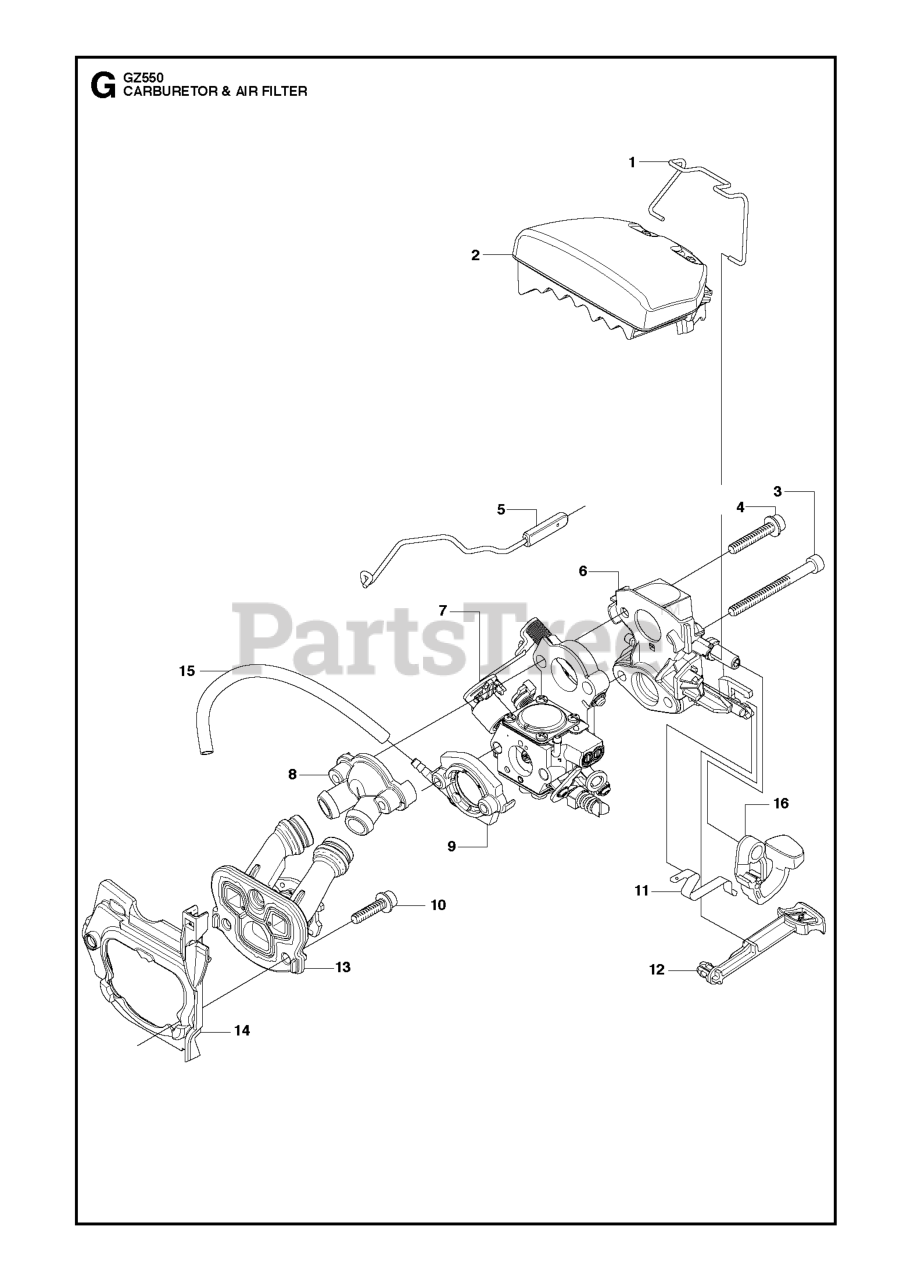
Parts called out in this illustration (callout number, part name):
2	AIR FILTER
5	THROTTLE ROD
6	FILTER HOLDER
7	CARBURETOR
11	SHORT CIRCUIT SPRING
12	CHOKE CONTROL
13	INDUCTION MANIFOLD
14	PARTITION
15	FUEL HOSE
16	STOP LEVER
